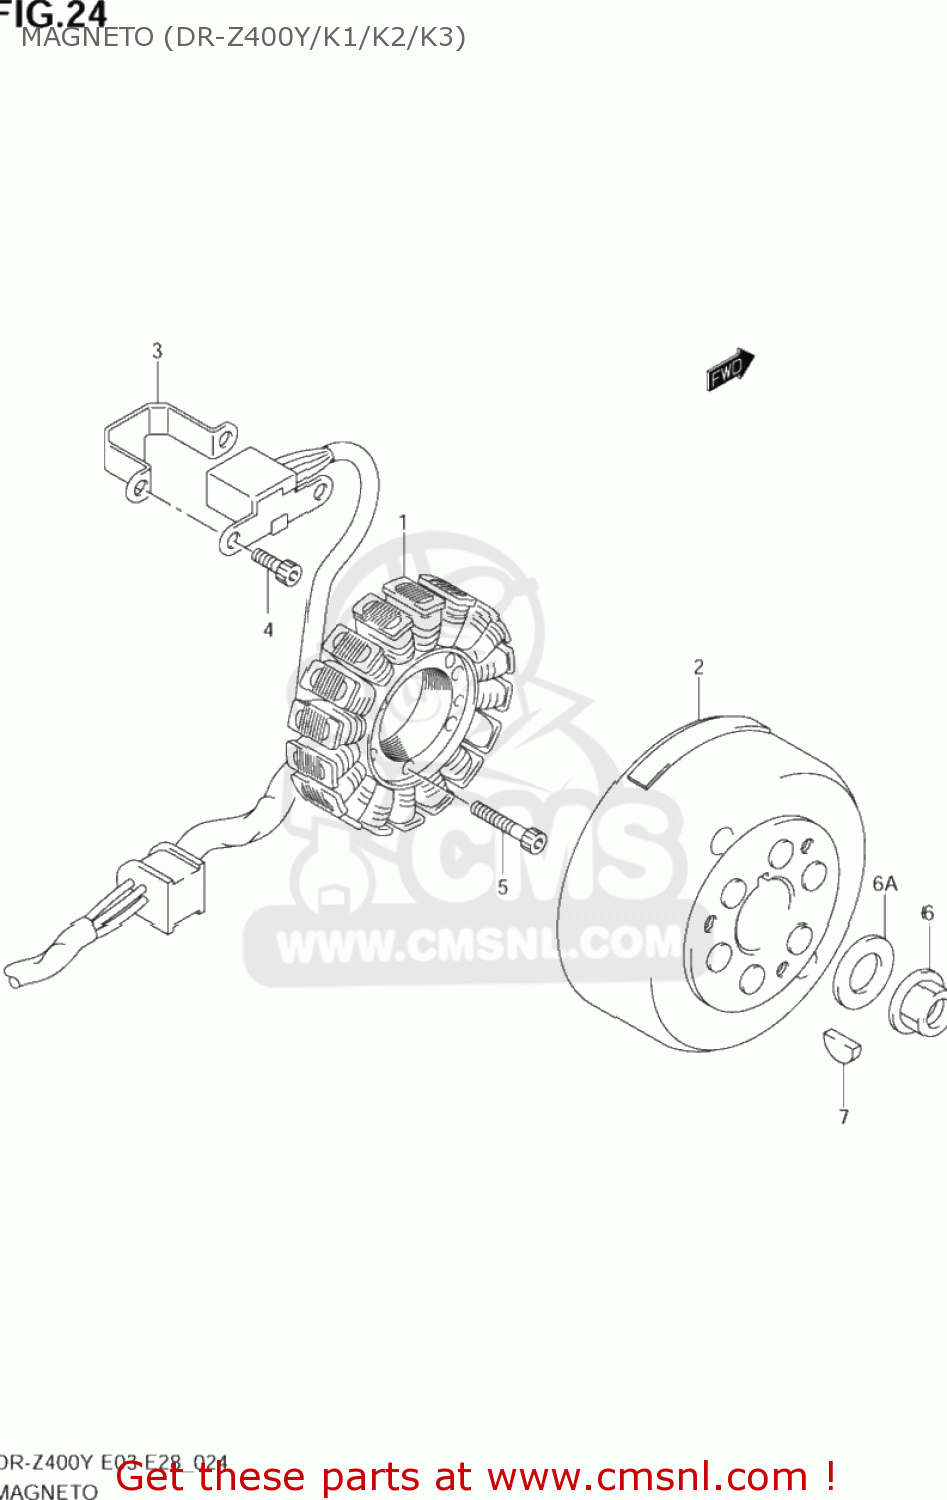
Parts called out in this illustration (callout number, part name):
1	STARTER ASSY
2	ROTOR ASSY
3	CLAMP,MAGNETO LEAD WIRE
4	BOLT
5	SCREW
6	NUT
6A	WASHER(12X27X2)
7	KEY
